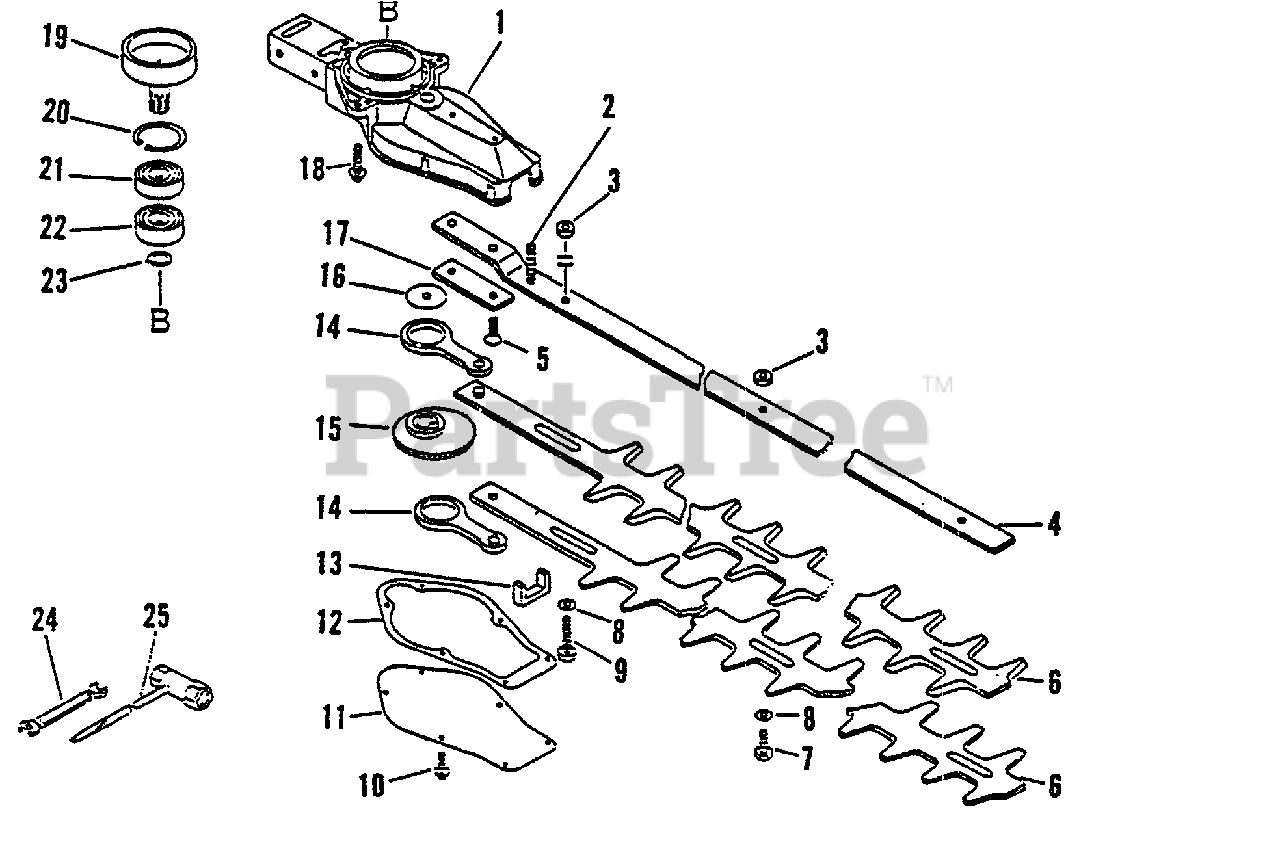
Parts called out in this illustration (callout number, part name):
1	CASE, GEAR
2	SCREW - 5X30
4	SUPPORT, BLADE
5	SCREW - 6X18
6	BLADE - 17" (43cm)
8	WASHER - 6
9	BOLT - 6X35
10	SCREW - 4X10
11	LID, GEAR CASE
12	GASKET, GEAR CASE
13	SEAL, FELT
14	ROD, CONNECTING
15	GEAR - DRIVE
18	SCREW - 5X20
19	DRUM, CLUTCH
20	RING, RETAINING - 35
21	BEARING, BALL - 6202
22	BEARING, BALL - 6202
23	RING, RETAINING - 14
24	T-WRENCH - 13X19mm
25	SPANNER - 8X10mm
